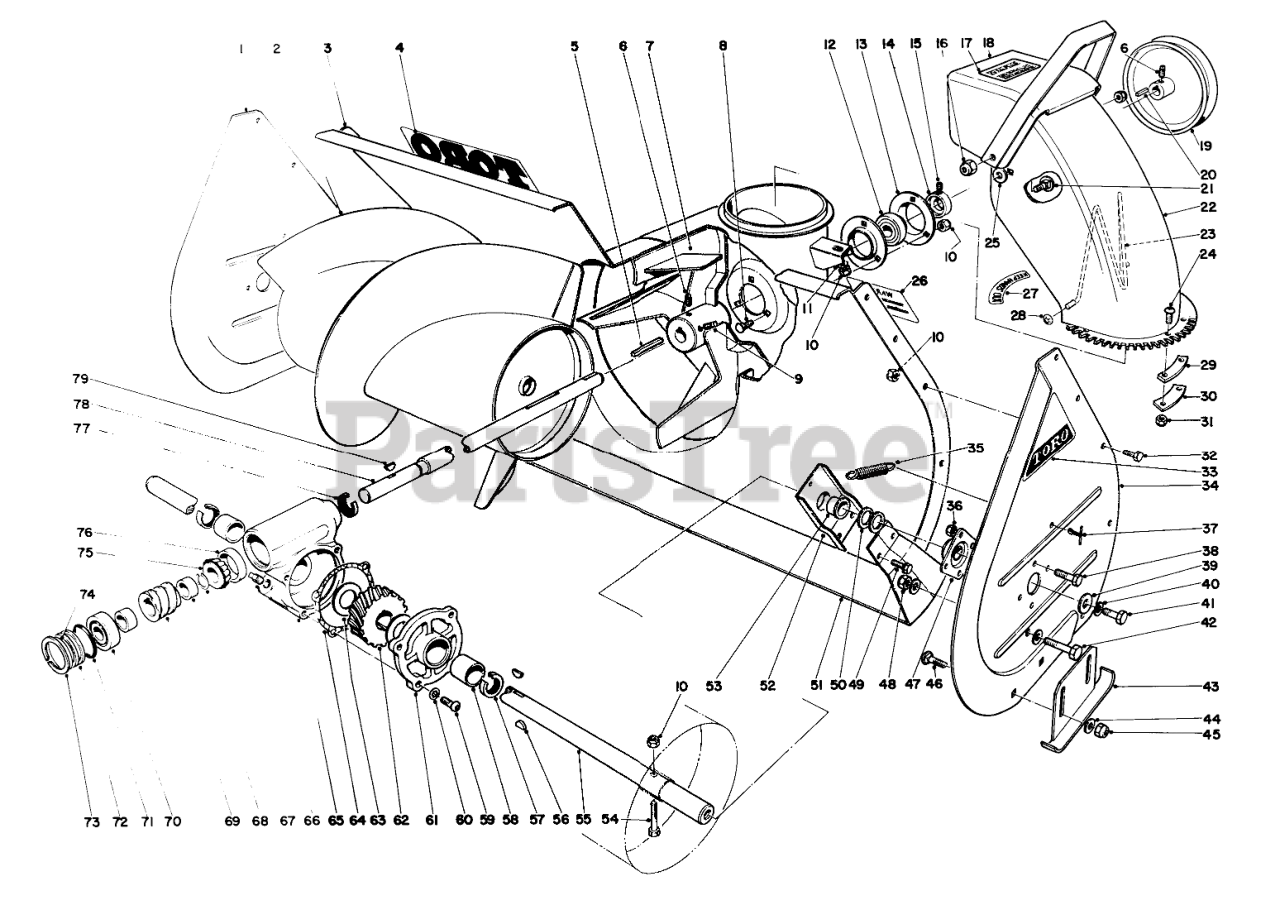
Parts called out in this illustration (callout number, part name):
1	Side Plate
2	Auger
3	Auger Housing
4	Decal
6	SCREW-SET, SQH
7	Impeller
8	BOLT-CARR
9	SCREW-SET, SQH
10	Nut
11	WASHER-LOCK
12	BALL BRG W/COLLAR
13	BRG FLANGE
14	EXT LOCKING COLLAR
15	SCREW-HSH
16	NUT-LOCK, NI
17	Decal
18	Deflector
19	1/2 X 9.5 DIA PULLEY
20	SQUARE KEY
21	SCREW-CARR
22	Upper Chute
23	WIRE-CHUTE
24	SCREW-HSBH
25	WASHER-FLAT
26	Decal
27	Decal
28	NUT-PUSH
29	CHUTE TAB SPACER
30	UPPER CHUTE TAB
31	Nut
32	SCREW-HH
33	Decal
34	Side Plate L. H.
35	SPRING-TENSION
36	NUT-LOCK
37	Retainer Spring
38	SCREW-HH
39	WASHER
40	WASHER-LOCK
41	SCREW-HH
42	SCREW-HH
43	Skid
44	WASHER-FLAT
45	NUT-LOCK, NI
46	BOLT-CARR
47	Bearing Flange
48	NUT-HEX
49	Hex Hd. Screw
50	Spacer
51	Scraper Blade
52	Mount, Scraper Blade (Incl.Ref. 53)
53	BUSHING-FLANGE
54	SCREW-HH
55	26 AUGER SHAFT
56	KEY-WOODRUFF
57	SEAL-OIL
58	Bushing
59	SCREW-HSBH
60	WASHER-LOCK
61	Cover, Gear Box (Incl. Ref. 58)
62	GEAR-WORM, 27T
63	WASHER-THRUST
64	Gasket
65	Gear Box, Auger (Incl. Ref 58 & 76)
66	PLUG-PIPE, SQH
67	RETAINER RING
68	Spacer
70	.750 BALL BEARING
71	O-RING
73	INTRNL RETAINING RING
75	3/4 ROLLER BRG CONE
76	1.750 ROLLER BRG CUP
77	SEAL-OIL
78	Shaft Worm
79	KEY-WOODRUFF
